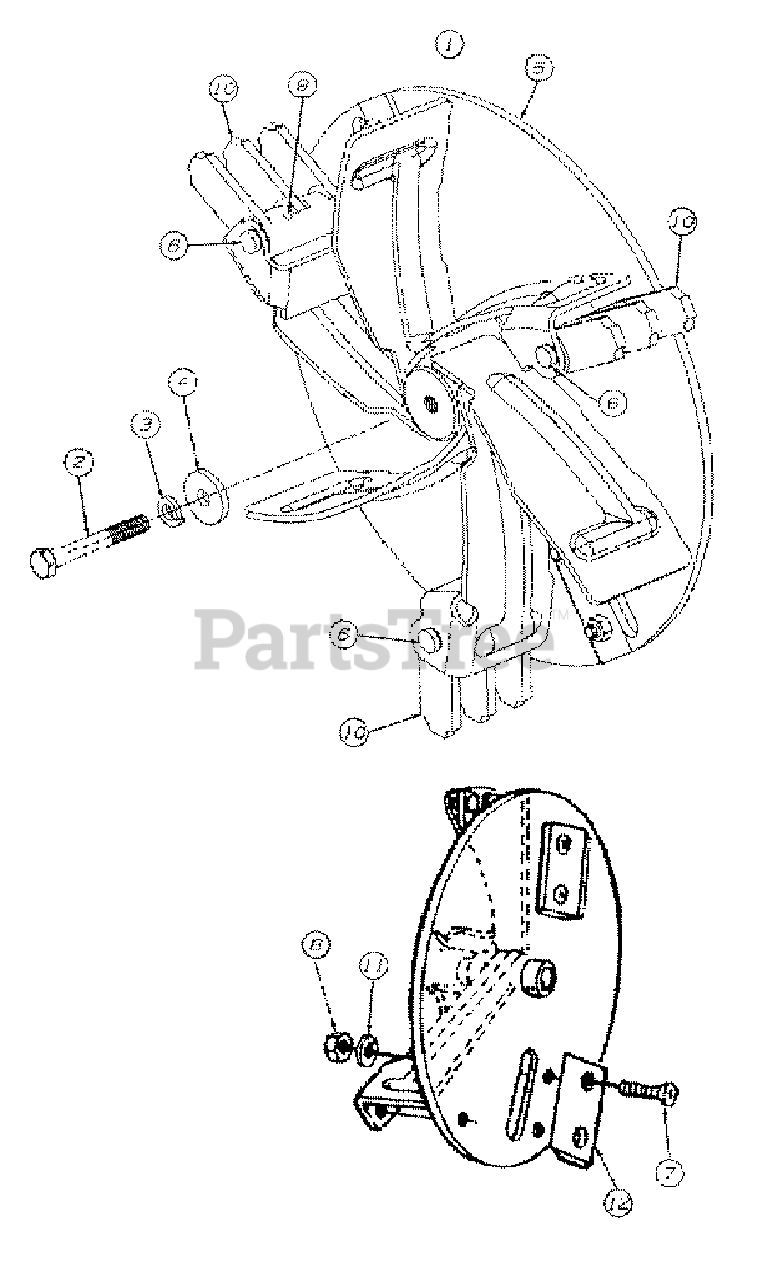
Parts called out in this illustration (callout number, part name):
1	IMPELLER ASS'Y COMP. (203B)
5	IMPELLER
6	PIN-CLEVIS
7	SCREW-FLAT HEAD
8	NUT-HEX LOCK
9	PIN-ROLL SPRING
11	WASHER-LOCK
12	BLADE-CHIPPER
